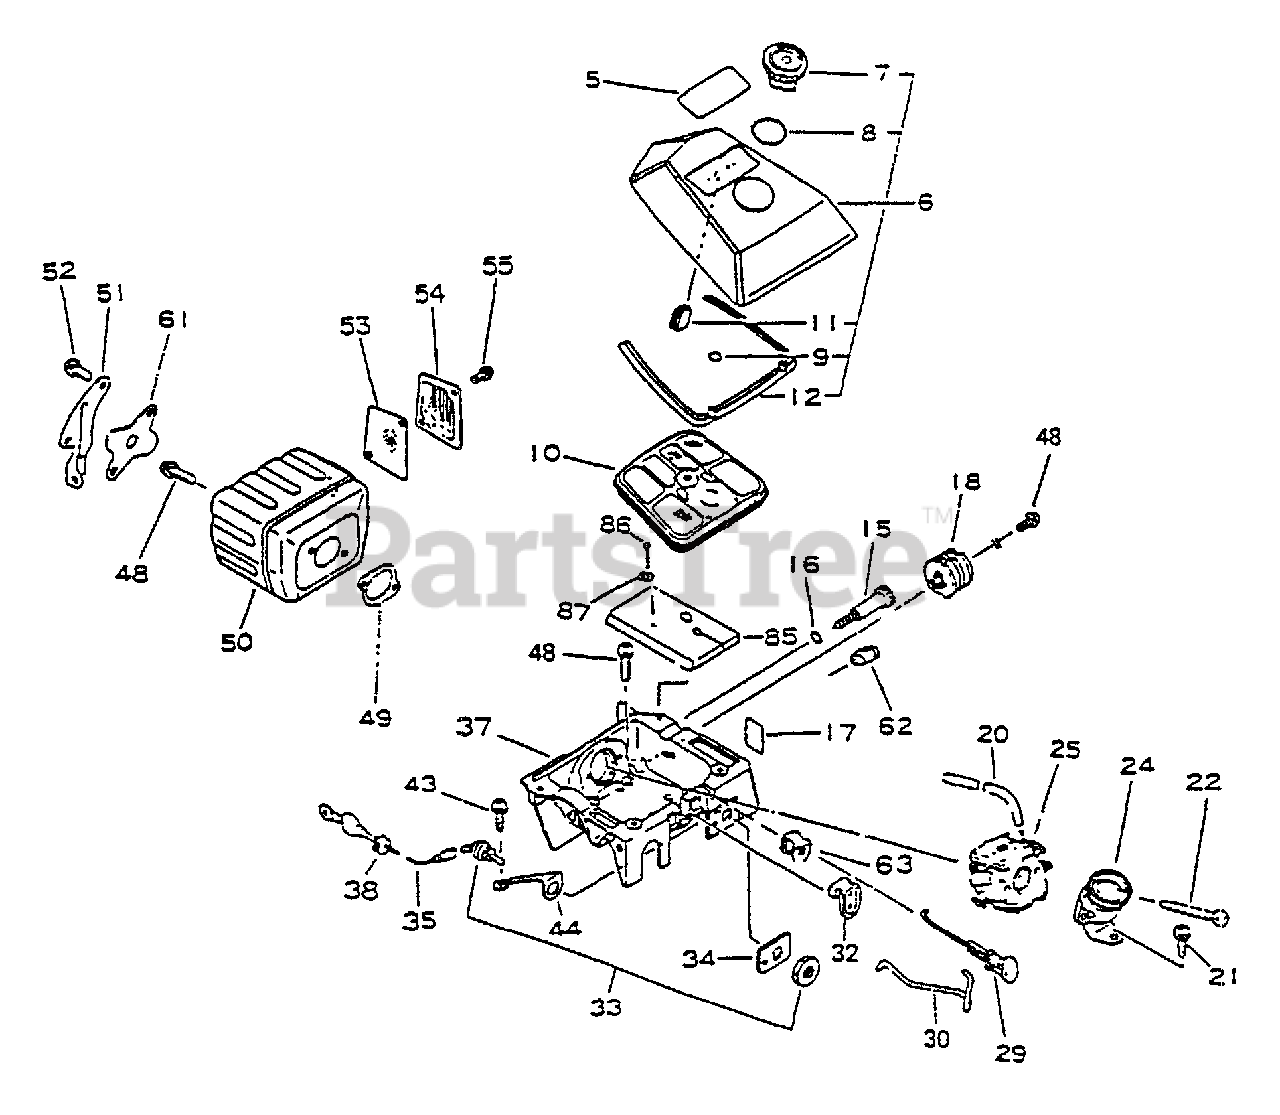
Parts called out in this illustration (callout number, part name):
5	LABEL, CS-6700
6	COVER ASSY, AIR FILTER
7	THUMBSCREW
8	O-RING 22
9	O-RING P-11
10	FILTER, FELT AIR
12	GASKET, AIR FILTER
15	SCREW, IDLE ADJUST - GRAY
16	O-RING 7 MM
17	LABEL, CAUTION
20	FUEL PIPE KIT
21	SCREW 5×14
22	SCREW 5×53
24	ADAPTOR, INTAKE
25	CARBURETOR
29	ROD, CHOKE
30	ROD, THROTTLE
32	ROD, THROTTLE
33	SWITCH, ON-OFF
34	LABEL, STOP
35	LEAD
37	CASE, CARBURETOR
43	BOLT 5×20
44	PLATE, GROUND
48	BOLT 5×20
49	GASKET, EXHAUST
50	MUFFLER
51	BRACKET, MUFFLER
52	SCREW 5×14
53	SCREEN, SPARK ARRESTER
54	OUTLET, EXHAUST
55	BOLT 4×10
61	COVER, MUFFLER
63	GROMMET
85	GASKET, CARBURETOR CASE
86	PIN, COTTER 3×18
